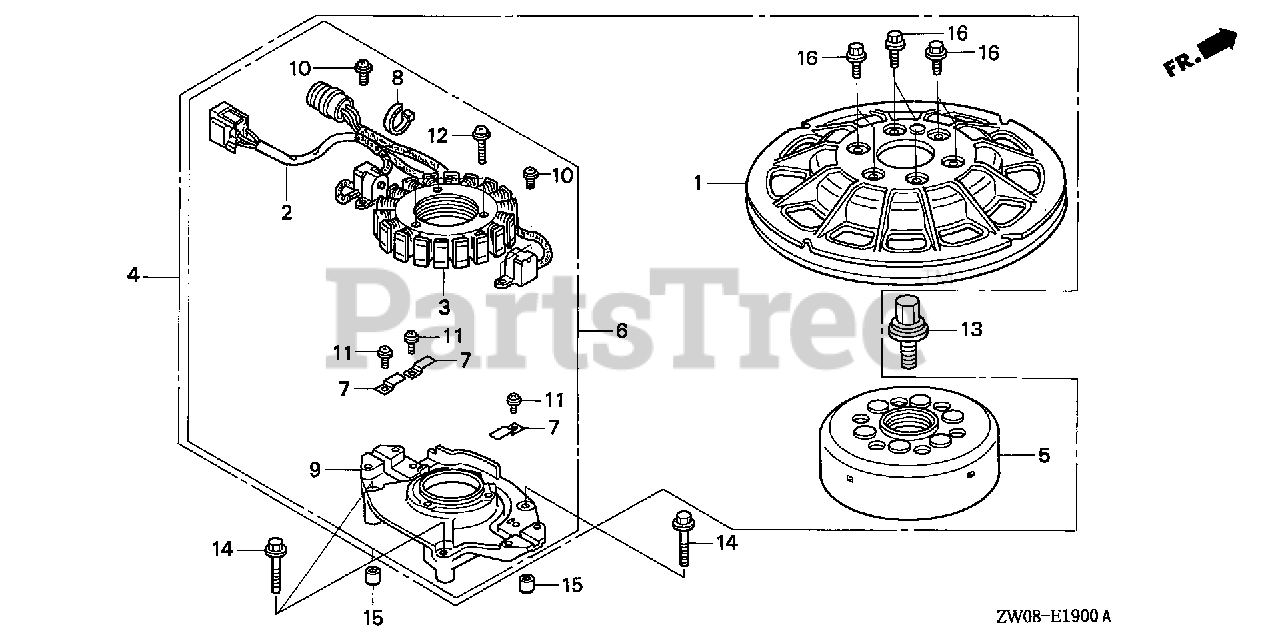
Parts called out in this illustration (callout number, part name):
1	PULLEY, STARTER
2	COIL ASSY., PULSER
4	ALTERNATOR ASSY.
6	STATOR ASSY.
7	CLAMP, WIRE
8	CLAMP, CABLE
9	BASE, COIL SETTING
10	SCREW-WASHER (5X12)
11	SCREW-WASHER (4X8)
12	SCREW-WASHER (6X30)
13	BOLT-WASHER (14X36)
14	BOLT, FLANGE (6X42)
15	PIN A, DOWEL (8X10)
16	BOLT, FLANGE (6X18)
